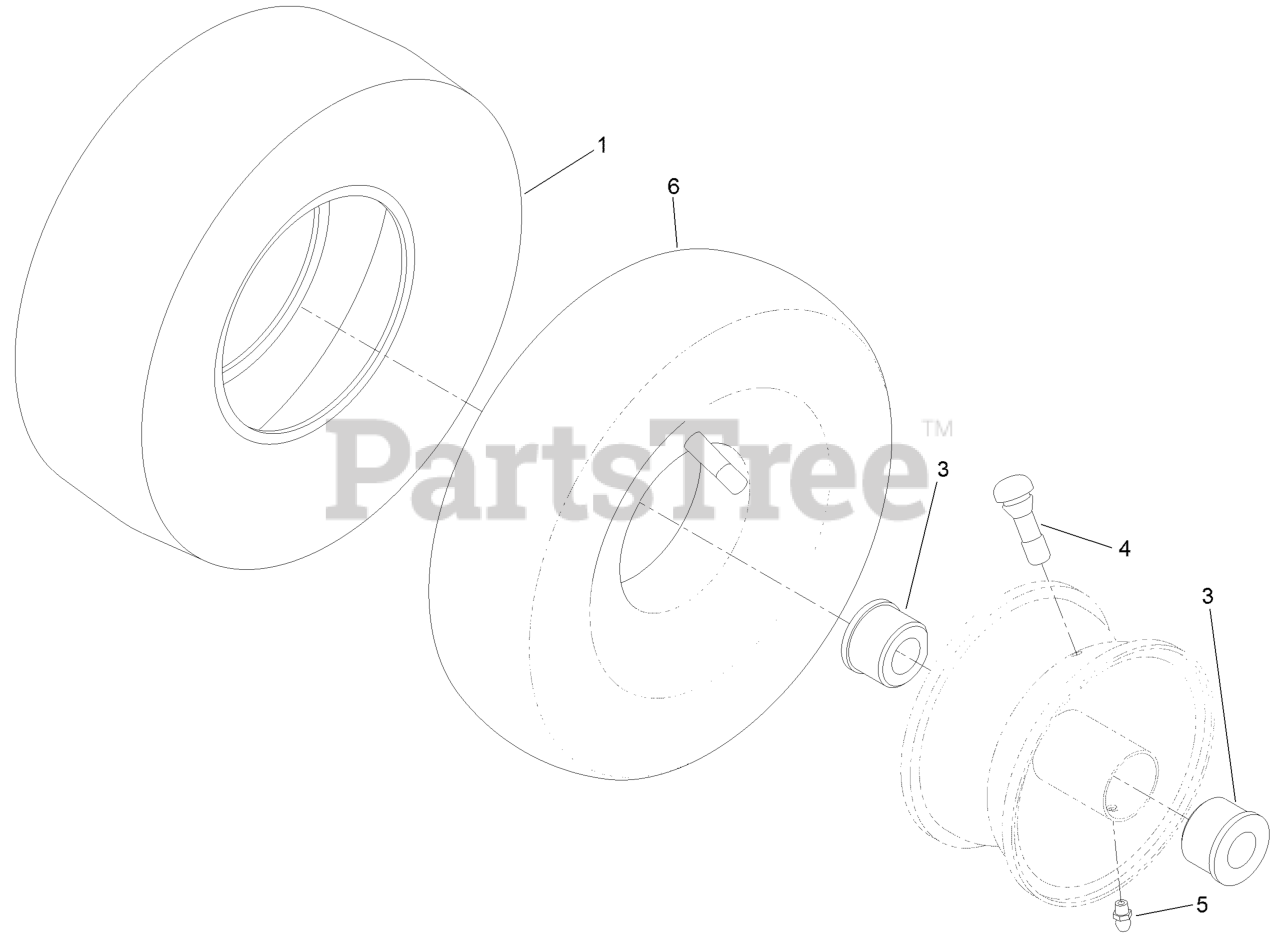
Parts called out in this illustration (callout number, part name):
2	BUSHING-FLANGE
3	Stem-Valve
4	FITTING-GREASE
5	TUBE-INNER
